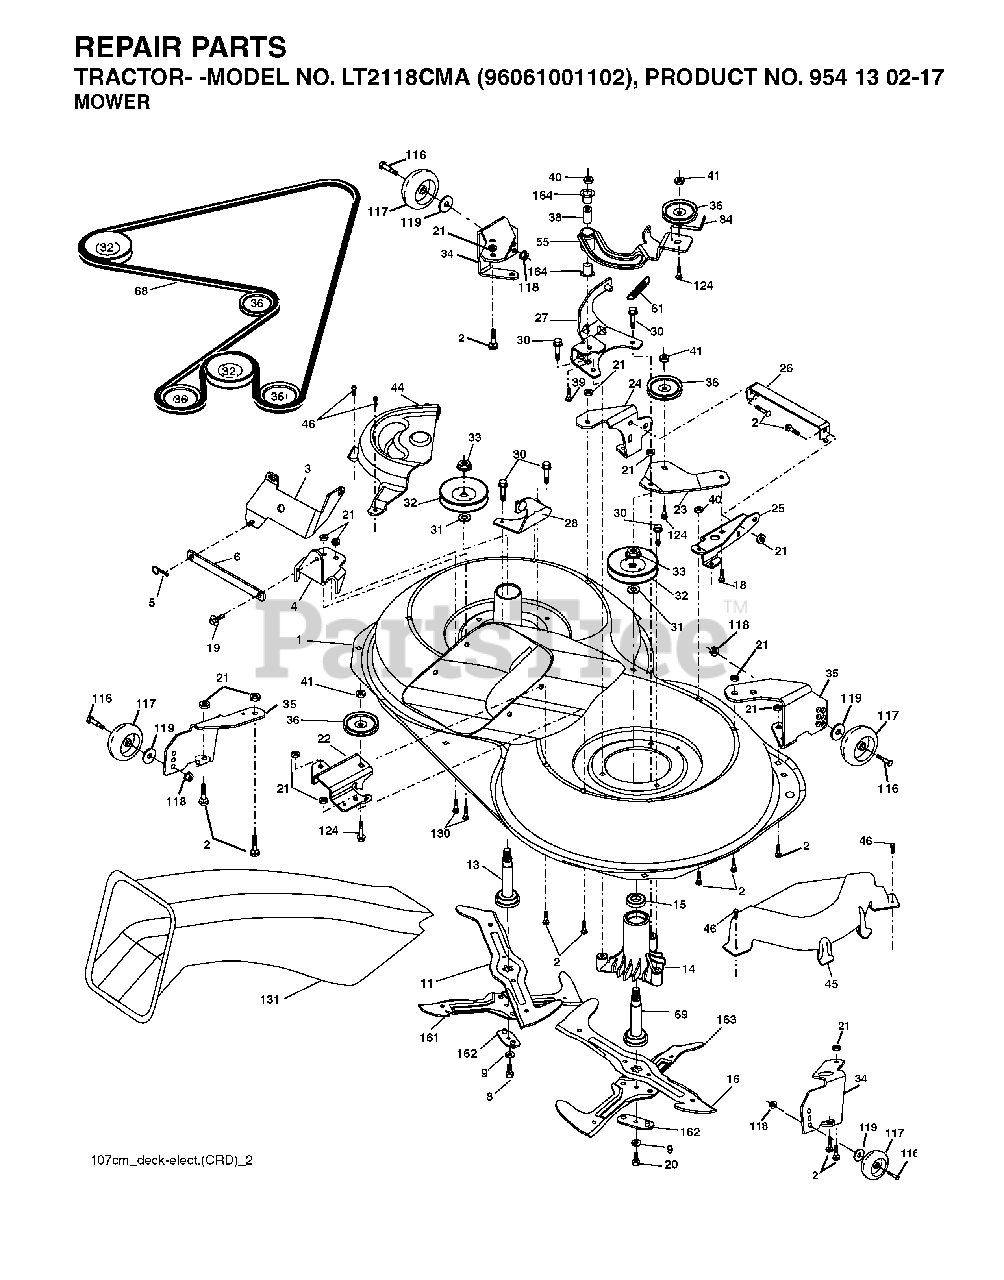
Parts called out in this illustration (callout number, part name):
2	BOLT
3	BRACKET
5	RETAINER-SPRNG RB
6	BAR SWAY
9	LOCKWASHER
11	BLADE.3N1.LH.CRD
13	SHAFT ASM VENT
14	HSG MANDREL
16	BLADE.3N1.RH.CRD
19	BOLT SHD 5/16-18
21	LOCKNUT
22	BRACKET
23	BRACKET
26	BRACE
27	BRACKET
30	SCREW, WASHER HEAD
31	WASHER.SPACER.MANDREL
33	NUT, FLG TOPLOCK 9/16"
36	PULLEY.IDLER.4.25
40	LOCKNUT
41	NUT LOCK FLG 3/8-16 UNC
45	MANDREL COVER
46	SCREW.1/4-20X5/8
55	ARM IDLER
68	HEX-BELT 107 MOWER
69	SHAFT.ASM.W/LWR.BRG.RH.THREAD
84	KEEPER, BELT IDLER
116	SHOULDER BOLT
117	WHEEL GAGE DONUT
118	LOCKNUT
119	WASHER
124	BOLT.3/8-16X1.50
131	CHUTE BAGGER
164	BRNG T
